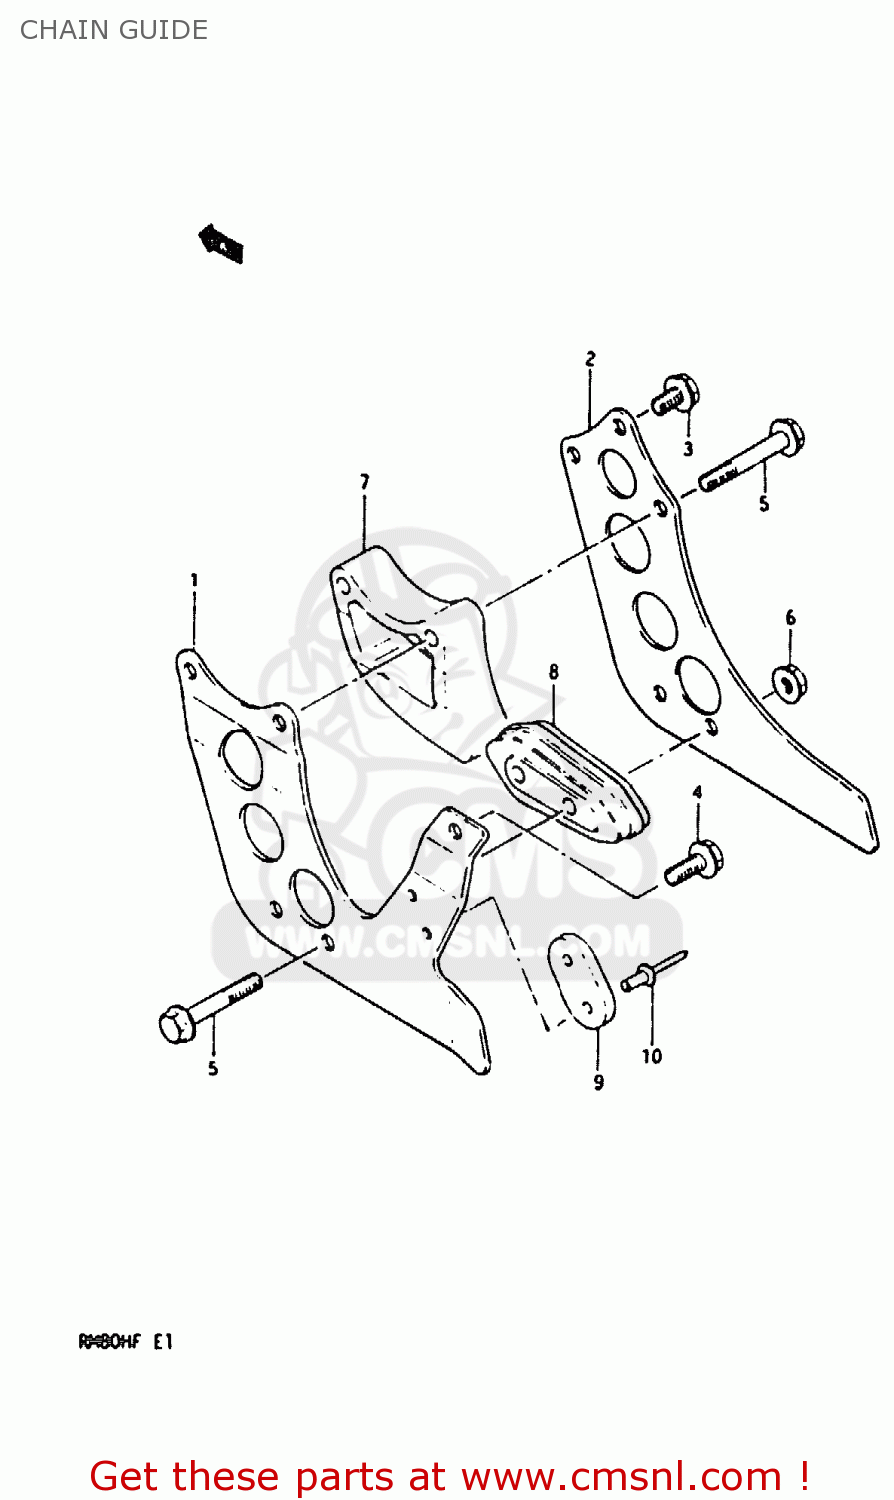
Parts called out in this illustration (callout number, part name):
1	PLATE,OUTER
2	PLATE,INNER
3	BOLT
4	BOLT
5	BOLT
6	NUT
7	DEFENSE,CHAIN GUIDE UPR
8	DEFENSE,CHAIN GUIDE
9	PAD,CHAIN GUIDE
10	RIVET
